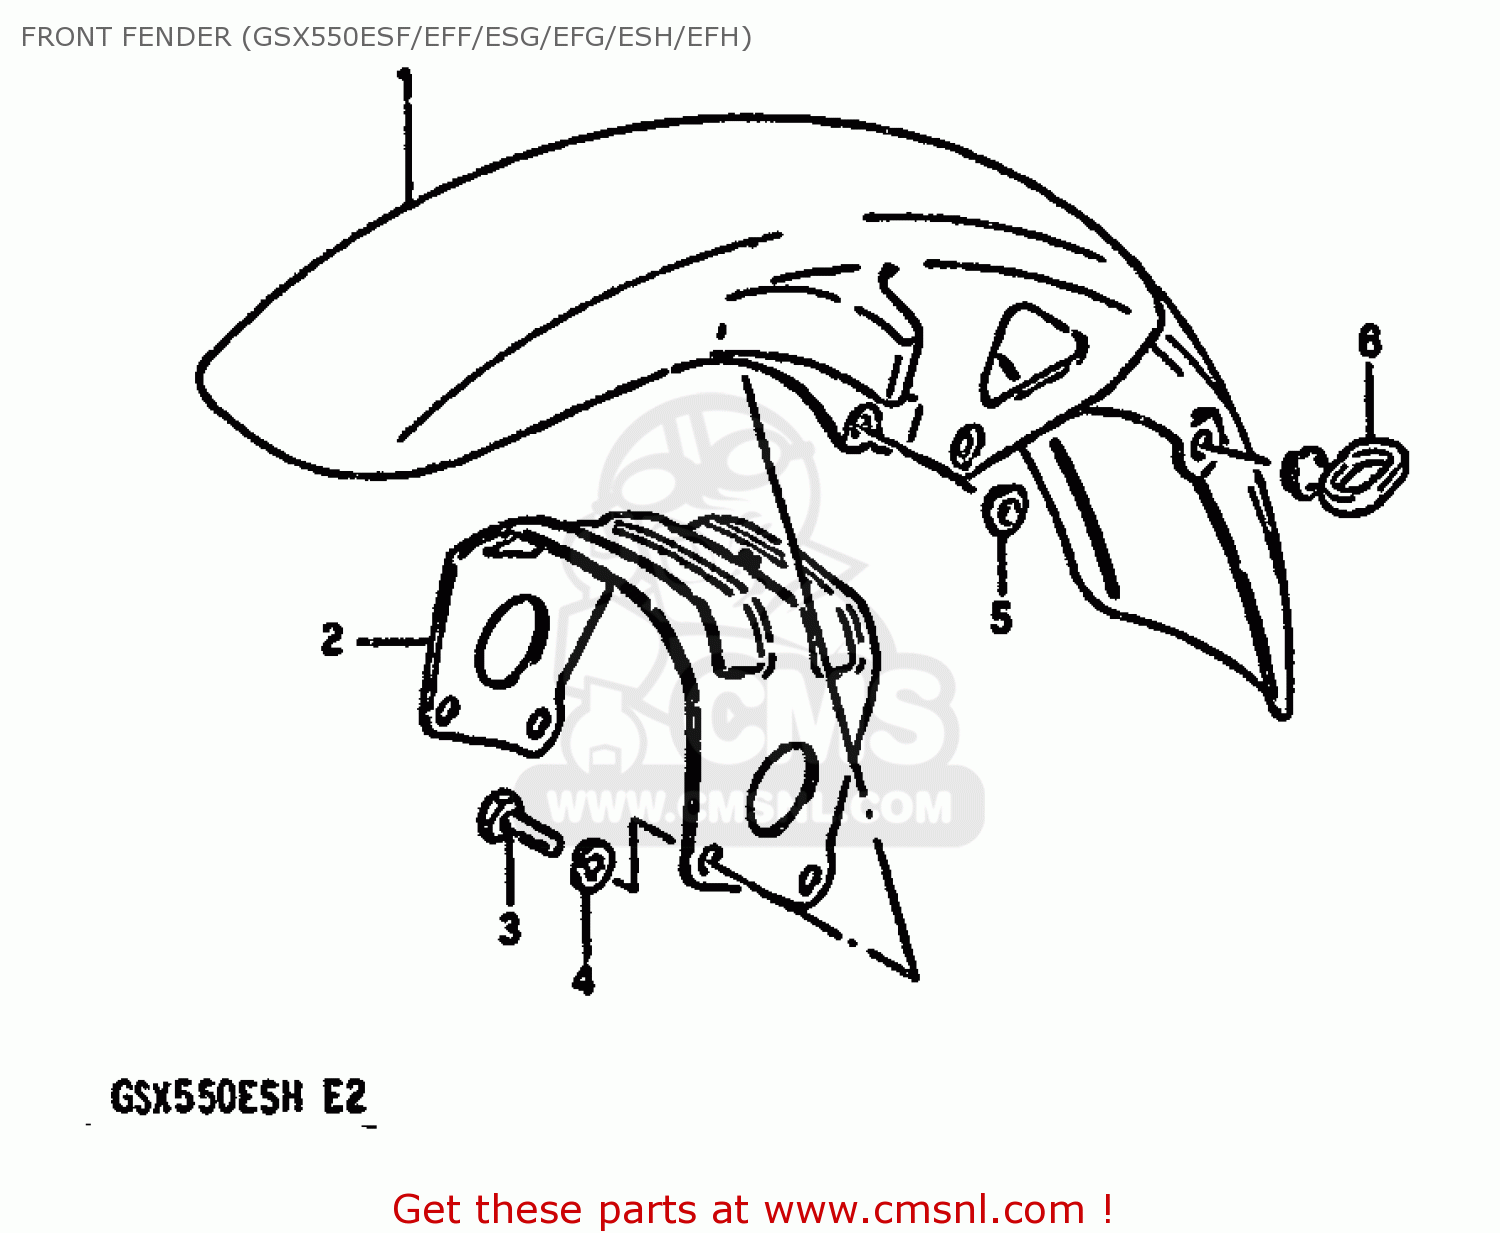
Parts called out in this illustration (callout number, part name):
1	FENDER,FRONT
2	BRACE,FRONT FENDER
3	BOLT,8X16
4	LOCK WASHER
5	WASHER
6	GUIDE,CABLE
